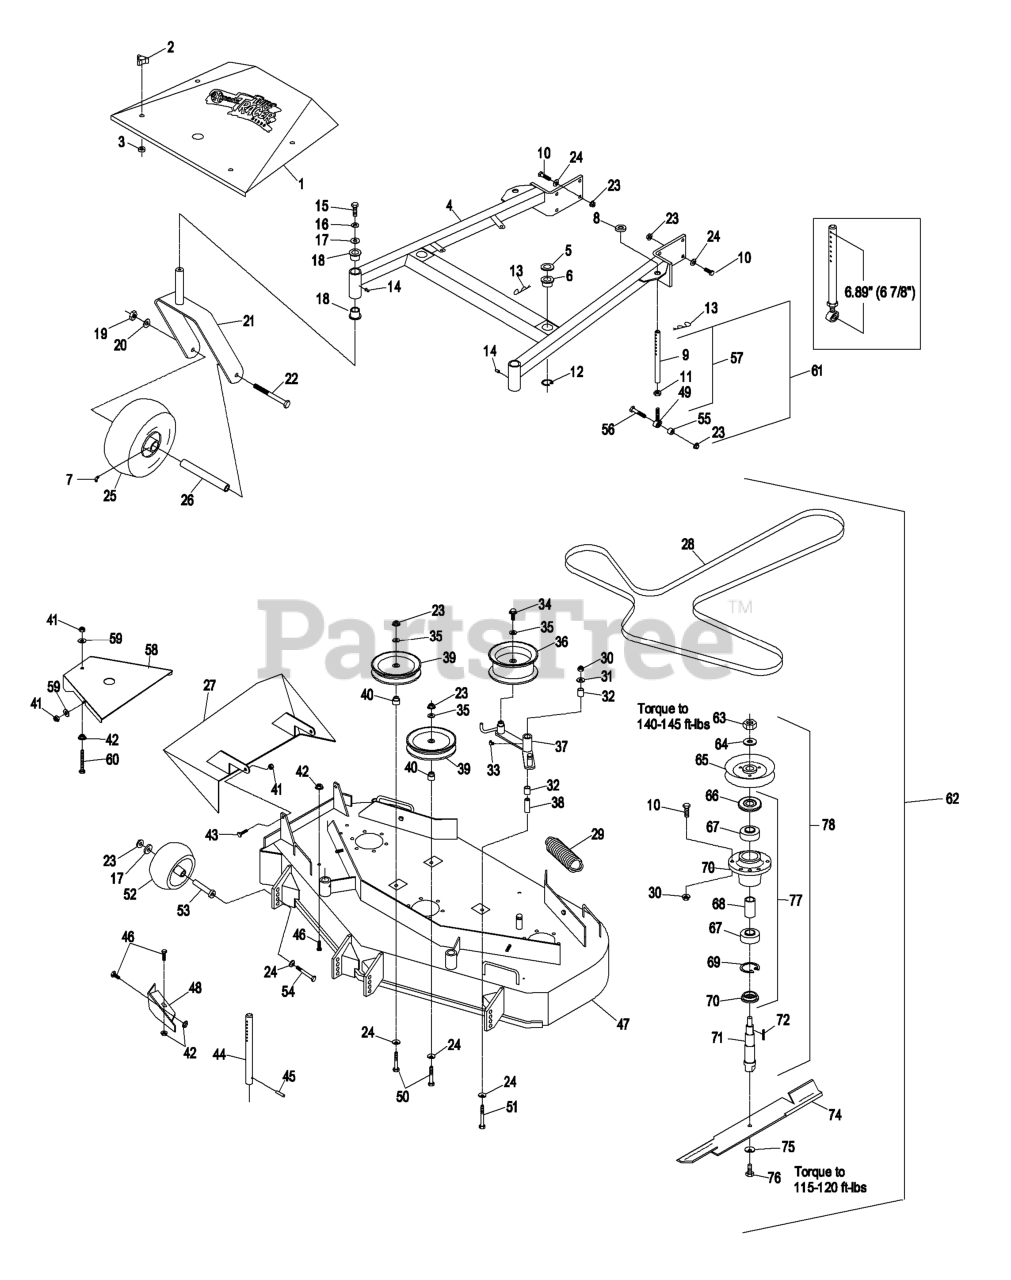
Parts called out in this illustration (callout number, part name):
2	KNOB-3 PRONG
4	DECK SUPPORT W/BSHGS 48"
5	SPACER-DECK SUPPORT
6	BUSHING-DECK
7	FITTING-GREASE
9	LINK,SUPPORT
10	SCREW-HH
11	NUT-HEX
12	RING-RETAINING
13	PIN,HAIR COTTER
14	FITTING-GREASE
15	SCREW-HH
16	WASHER-LOCK
18	BEARING-FLANGED
19	NUT-HH
20	WASHER-LOCK
22	SCREW-HH
23	NUT-HHF, WHIZ
24	WASHER-BELLEVILLE
26	SPACER FRONT CASTER
27	WLD,DISCHARGE CHUTE 36/48
28	BELT - V, B
30	NUT-LOCK, NI
31	WASHER-FLAT
32	SLEEVE-BEARING
33	FITTING-GREASE, 90 DEG
34	SCREW-HHF
35	WASHER-FLAT
38	BUSHING-PIVOT, IDLER
39	PULLEY-IDLER
40	BUSHING-IDLER
41	NUT-LOCK, NI
43	SCREW-HH
44	ROD,DECK SUPPORT
46	SCREW-HH
47	ASM,DECK W/DECALS TTHP/MH
49	BALLJOINT
50	SCREW-HH
51	SCREW-HH
52	ROLLER-SCALP, ANTI
53	BUSHING-ROLLER
54	SCREW-HH
56	SCREW-HH
58	SHIELD,BELT
59	WASHER-FLAT
60	BOLT,TAP HH
62	Assy, Cutting Deck Complete
65	SHEAVE,W/HUB 5.72
66	GUARD-BEARING, TOP
67	BEARING-JACKSHAFT
68	SPACER-BEARING
69	RING-SNAP
70	SPACER-GUARD, BOTTOM
71	SPINDLE,SHAFT
72	KEY-RECTANGLE
75	WASHER-SPRING
76	SCREW-CAP
79	KIT, SP CASTER WHEEL REPL
